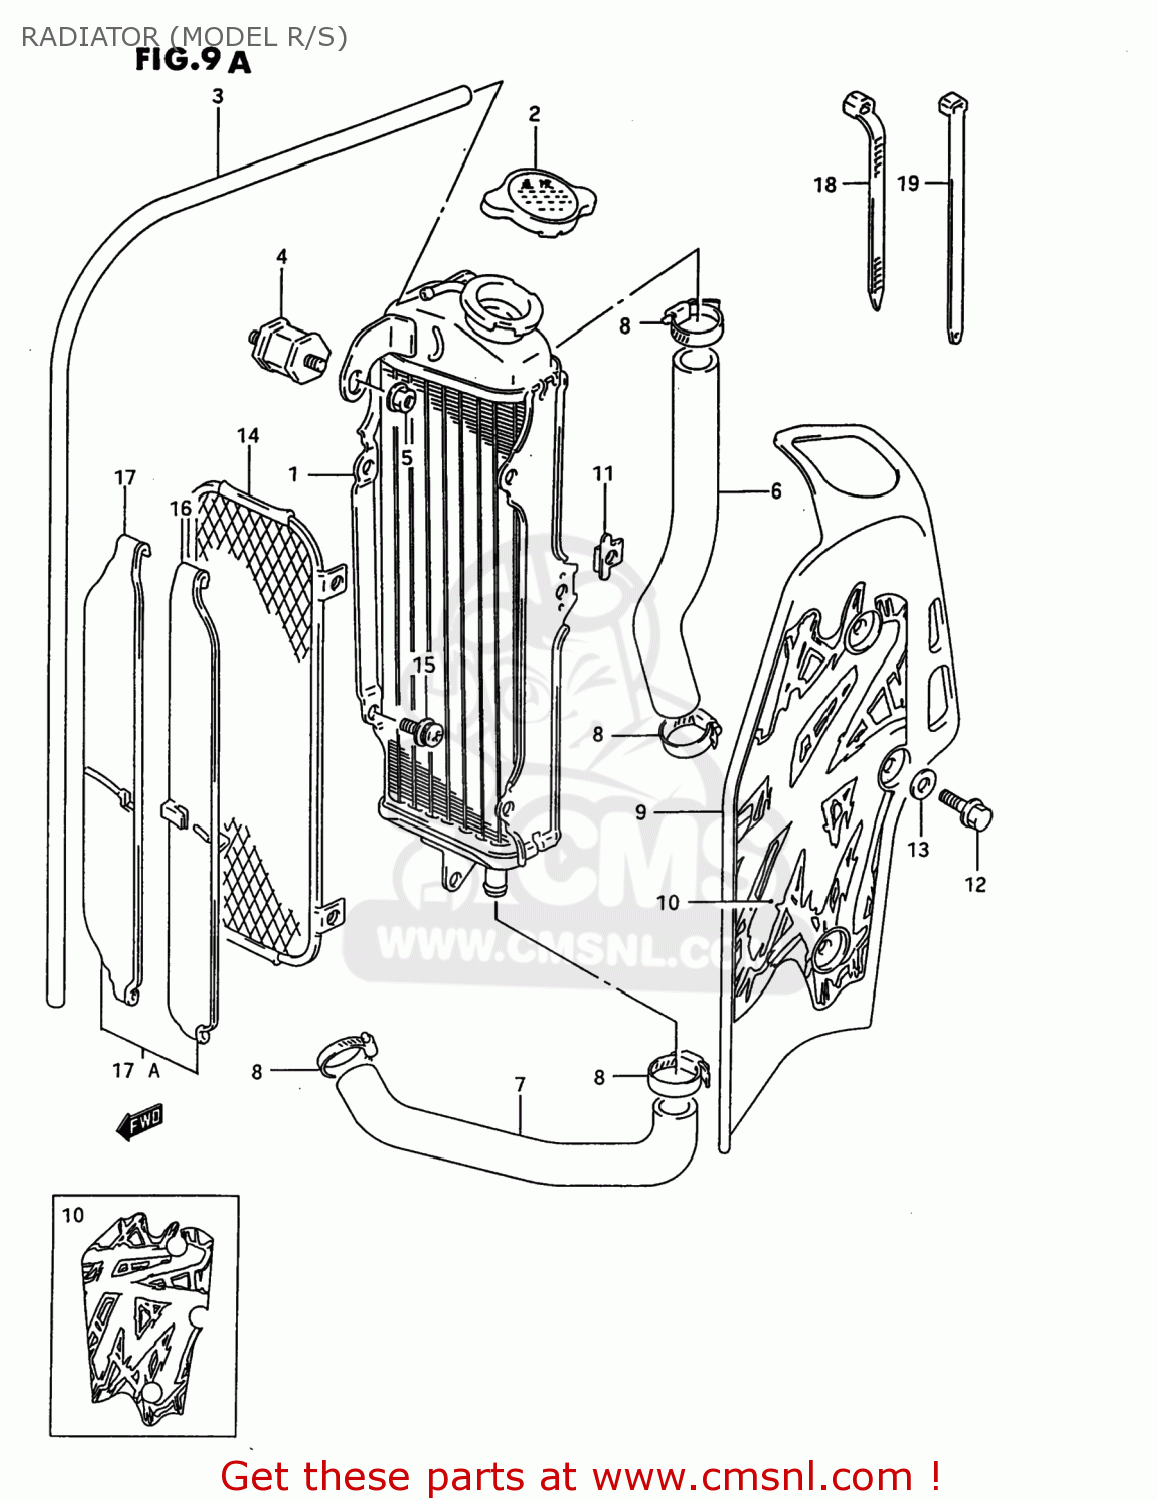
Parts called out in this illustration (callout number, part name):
1	RADIATOR COMP,WATER
2	CAP,RADIATOR
3	HOSE (5X8X600)
4	BOLT,RADIATOR CUSHION
5	NUT
6	HOSE,RADIATOR INLET
7	HOSE,RADIATOR OUTLET
8	CLAMP
9	COVER,RADIATOR
10	EMBLEM,RADIATOR COVER
11	PLATE,RADIATOR COVER FITING
12	BOLT
13	WASHER(6.5X18X1)
14	BUMPER,RADIATOR
15	SCREW
16	LOUVER,RADIATOR,OUTER (
17	LOUVER,RADIATOR,INNER (
17A	LOUVER,RADIATOR (BLACK)
18	CLAMP(L:235)
19	CLAMP
